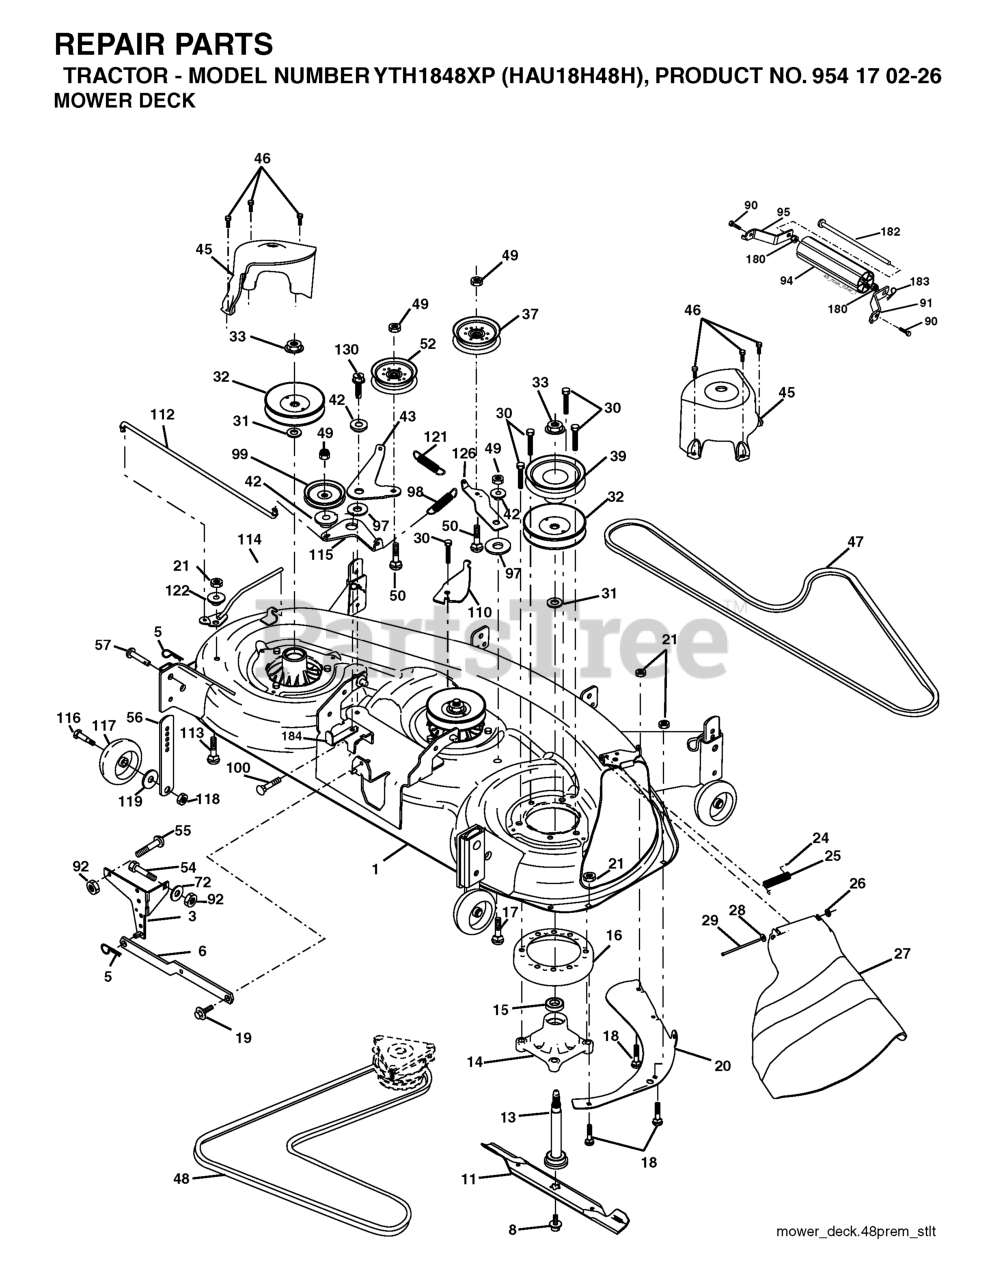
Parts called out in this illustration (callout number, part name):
1	DECK WELDMENT MOWER, 48
3	BRKT ASM SWAY BAR
5	RETAINER-SPRNG RB
6	BAR SWAY DECK
8	BOLT 7/16 ASM BLADE
11	48" HI-LIFT BLADE
13	SHAFT ASM W/LOWER BEARING
14	HOUSING, MANDREL 48"
16	STRIPPER.MANDREL.ROUND.BLACK
17	BOLT
18	BOLT
19	BOLT SHD 5/16-18
20	BAFFLE, VORTEX MWR
21	LOCKNUT
24	CAP-SLEEVE LT
25	SPRING, TORSION
26	NUT PUSH M
27	DEFLECTOR SUBS TO 532 180655
28	Washer 11/32 x 5/8 x 16 Ga SD
29	ROD.HINGE
30	SCREW, WASHER HEAD
31	WASHER.SPACER.MANDREL
32	PULLEY, MANDREL
33	NUT, FLG TOPLOCK 9/16"
36	WASHER
37	PULLEY.IDLER.FLAT
39	PULLEY.DRIVEN.DECK.48'
42	SPACER RETAINER
43	ARM, IDLER SECONDARY
45	COVER.MANDREL.DECK.48"
46	SCREW.1/4-20X5/8
47	V-BELT, 48"SECONDARY
48	V-BELT PRIMARY 48"
49	NUT LOCK FLG 3/8-16 UNC
50	BOLT.3/8-16X1.50
52	PULLEY.IDLER.FLAT.46.PR.DR.
55	BOLT D
56	BAR.ADJUST.WHEEL.ANTI.SCALP.BL
57	RIVET.PIN.HEAD.YELLOW.
72	WASHER
90	BOLT RB
91	BRKT.NOSEROLLER.RH.48"
92	NUT
94	NOSE ROLLER 48"
95	BRKT.NOSEROLLER.LH.48"
98	SPRING PRIMARY DRIVE
99	IDLER PULLEY
110	ARM, SPRING SECONDARY
112	LEVER, TENSION RELIEF LINK
113	BOLT.CARR.SQNK.5/16-18UNC.X3/4
114	TENSION ASM RELIEF LEVER
115	ARM, SPRING TENSION RELIEF
116	SHOULDER BOLT
117	WHEEL GAGE DONUT
118	LOCKNUT
119	WASHER.5/16.FLAT.STE.STD.
121	SPRING.DRIVE.SECONDARY.48".DEC
122	BUSHING, PIVOT TENSION RELIEF
126	ARM, IDLER PRIMARY DECK
130	SCREW 3/8-16X1
180	NUT.71038.31-18.HEX.NYLOCK
182	ROD.ROLLER.NOSE.NARROW.48"
183	SPRING RETAINER
184	KEEPER BELT IDLER PLATED
